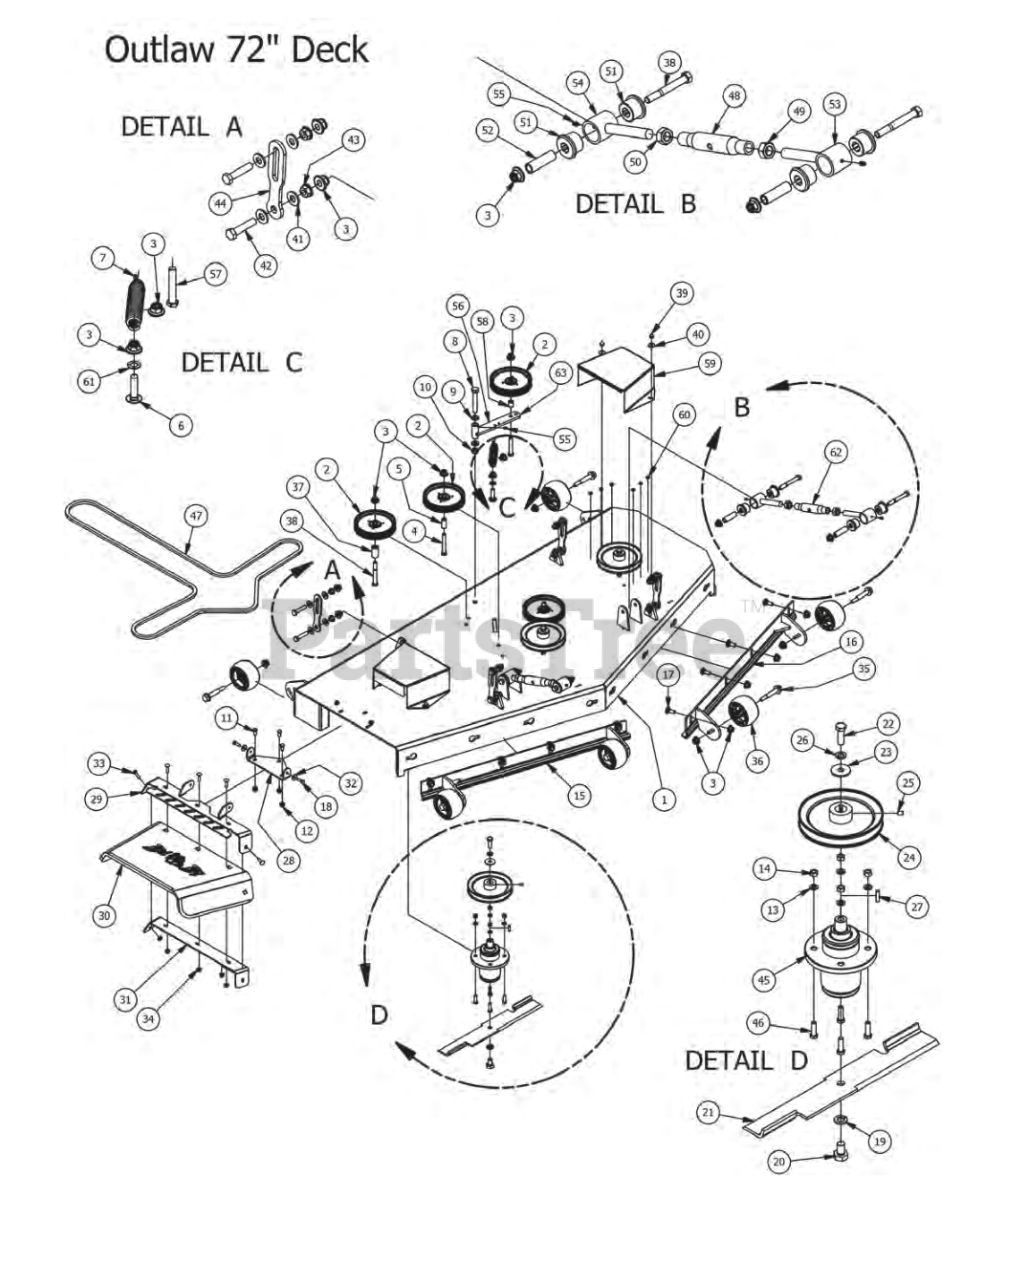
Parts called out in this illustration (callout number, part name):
1	2015 72" Deck
2	5-3/4 Idler Pulley
3	1/2-13 Nylon Flange Nut-Orange
4	1/2 x 3 1/2 Flange Bolt Grade 8
5	.502 ID X.75 OD X 1.500 Leng
6	1/2 x 2" Carriage Bolt
7	2015 Deck Idler Spring Outlaws
8	5/8" x 4" Hex Bolt
9	.635 ID Plastic Washer
10	5/8-11 Nylon Insert Jam Half Nut
11	3/8" x 3/4" Hex Bolt
12	3/8" Flange Nut
13	3/8 Lockwasher Zinc
14	3/8-16 Hex Nuts Zinc
15	72" Deck Adustable Front (Right)
16	72" Deck Adjustable Front (Left)
17	1/2" x 1 1/4 Carriage Bolt
18	5/16" x 1" Bolt
19	5/8" Lock Washer
20	5/8" x 1 1/2" Gr8 Hex Bolt (Fine)
21	72" High Lift Fusion Blade
22	1/2"-20 x 1 1/2-Grade 5 Fine Thread Bolt
23	1/2 Belleville Washer
24	7 Deck Pulley
25	5/16 Set Screw
26	1/2" Lock Washer
27	1/4" x 1" Key
28	Discharge Chute Hanger (deck mounted)
29	60" Discharge Chute Upper Hanger
30	Rubber Discharge Chute
31	60" Discharge Lower Bracket
32	360 ID Plastic Washer
33	5/16" x 1 1/4" Carriage Bolt
34	5/16" Flange Nut Zinc W/Serrations
35	Deck Wheel Bolt
36	Anti-Scalp Rollers
37	13/4" Pulley Spacer
38	1/2" x 4" Bolt (Grade 8)
39	Acorn nut-pulley Cover
40	.360 ID Plastic Washer-Black
41	505 Nylon Spacer
42	1/2-13X 2-1/4 GR Hex Bolts
43	1/2" Flange Nut
44	Deck Hanging Tab
45	OUTLAW SPINDLE ASSEMBLY
46	3/8" x 1 1/4" Hex Bolt
47	B202 Belt for 72" Outlaw
49	3/4-10 Left-Handed Hex Nuts Zinc
50	3/4-10 Hex Nuts Zinc
53	Turn Left-Handed
54	Right-Handed End
55	1/4" Press in Grease Fitting
56	Deck Idler
57	1/2-13 x GR 5 Hex Bolt Zinc
58	3/4 OD x 1/2 ID x 3/4 Length
59	72 Spindle Cover
60	Black, Round Stick-On Rubber Bumpon
61	517 Square Hole Round Washer
62	Turnbuckle Assembly
63	Deck Idler Assembly-Includes parts: 3,9,59,60,61
